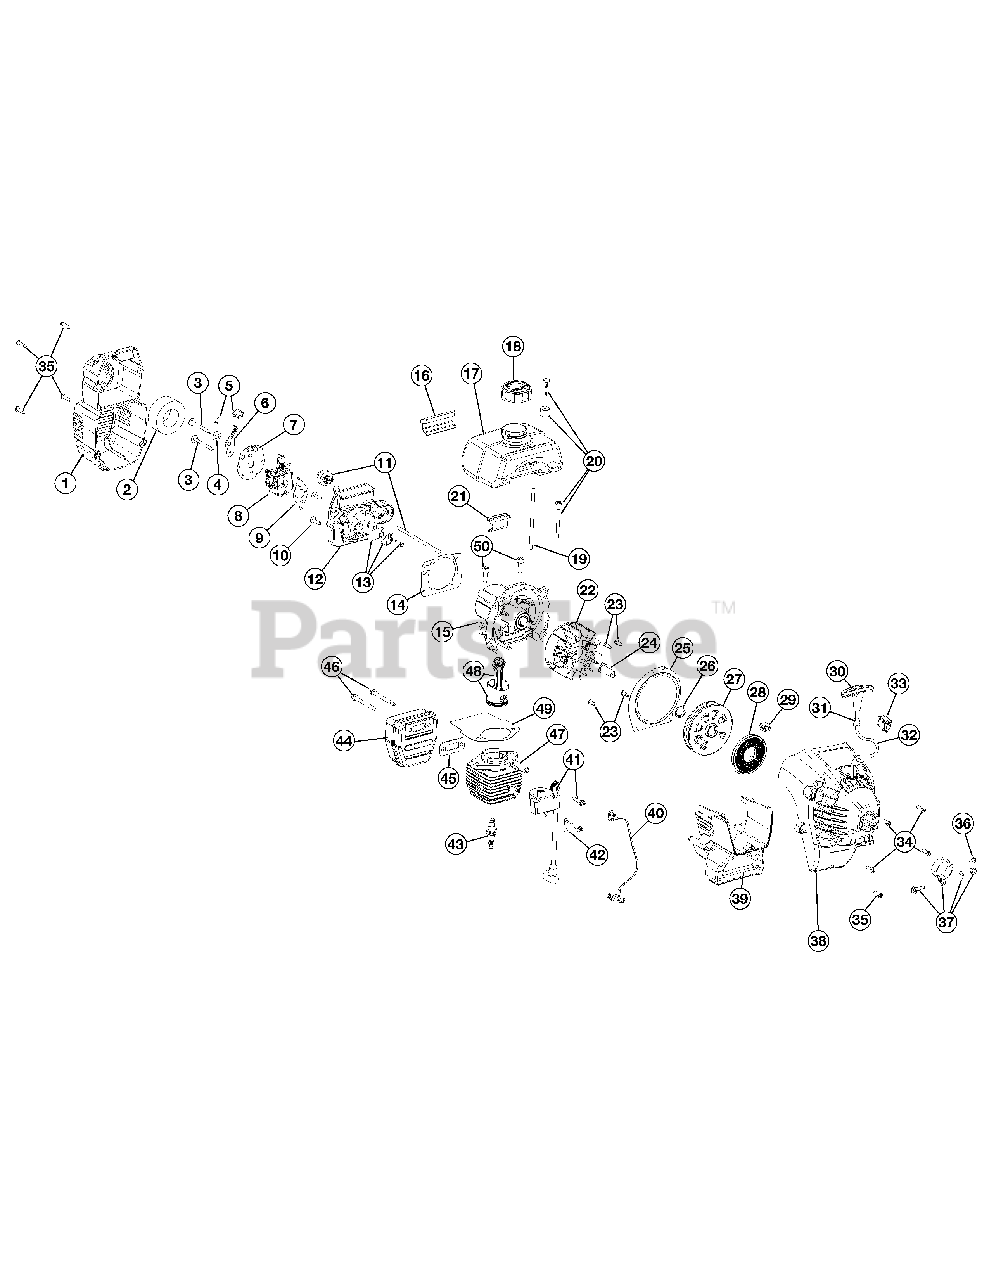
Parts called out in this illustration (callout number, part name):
1	Air Cleaner Cover Assembly (includes 2 & 35)
2	Air Cleaner Filter
3	Carburetor Mounting Screws
4	Wavey Washer
5	Choke Knob & Screw
6	Choke Lever Assembly (includes 5)
7	Choke Lever & Plate (includes 6)
8	Carburetor Assembly (includes 9 & 20)
9	Carburetor Gasket
10	Carb Mount Screw
11	Primer and Hose Assembly
12	Carburetor Mount Assembly (includes 10, 13 & 14)
13	Reed Assembly
14	Carburetor Mount Gasket
15	Crankcase Service Assembly (includes 10)
16	Rear Mounting Pad
17	Fuel Tank Assembly (includes 18 & 20)
18	Fuel Cap Assembly
19	Fuel Return Line
20	Fuel Line Assembly
21	Front Mounting Pad
22	Flywheel Assembly
23	Plate Screw
24	Square Nut Drive
25	Pressure Plate (includes 23 & 29)
26	Palnut
27	Recoil Pulley Assembly (includes 26 & 32)
28	Recoil Spring
29	Eyelet Retainer
30	Pull Handle
31	Rope Guide
33	Switch Assembly (includes 38)
34	Housing Screw
35	Cover Screw
36	Anti Rotation Screw
37	Clamp Assembly
38	Starter Housing Assembly (includes 23, 25-38)
39	Shroud Extension and Stand
40	Wire Lead
41	Module Assembly
42	Ground Tab
43	Spark Plug
44	Muffler Assembly (includes 46-51)
45	Exhaust Gasket
46	Muffler Mounting Bolt Assembly
47	Cylinder Assembly (includes 54 & 55)
48	Piston & Rod Assembly
49	Cylinder Gasket
50	Cylinder Bolt
